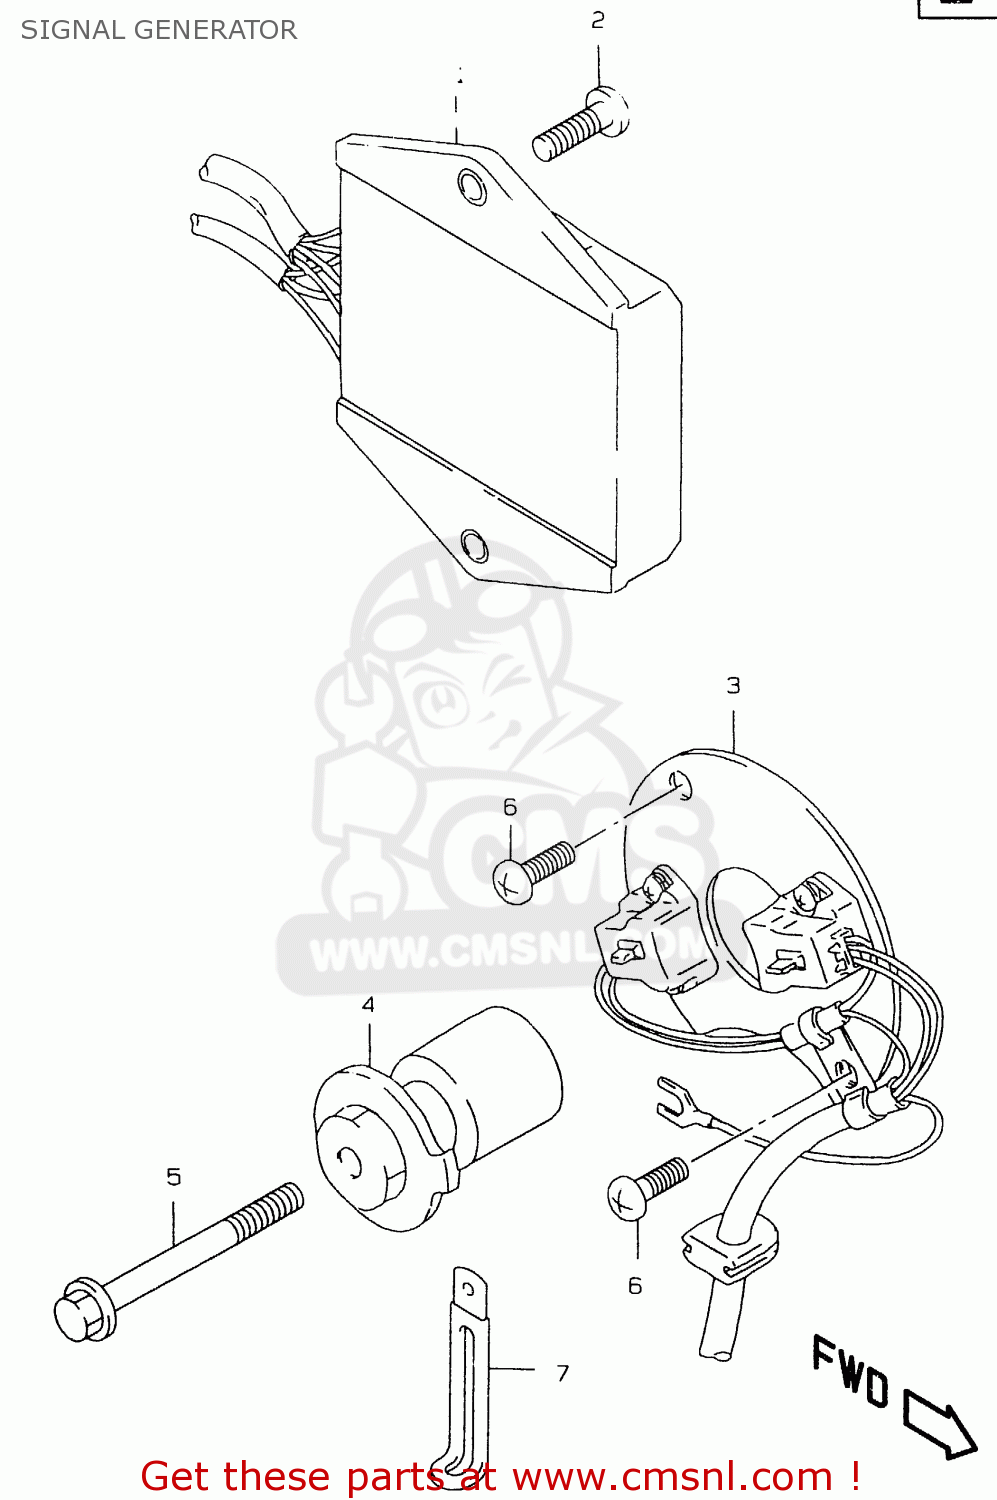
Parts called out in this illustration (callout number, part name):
1	IGNITER
2	SCREW
3	SIGNAL GENERATOR ASSY
4	ROTOR,SIGNAL
5	BOLT(6X60)
6	SCREW
7	CLAMP(L:65)
